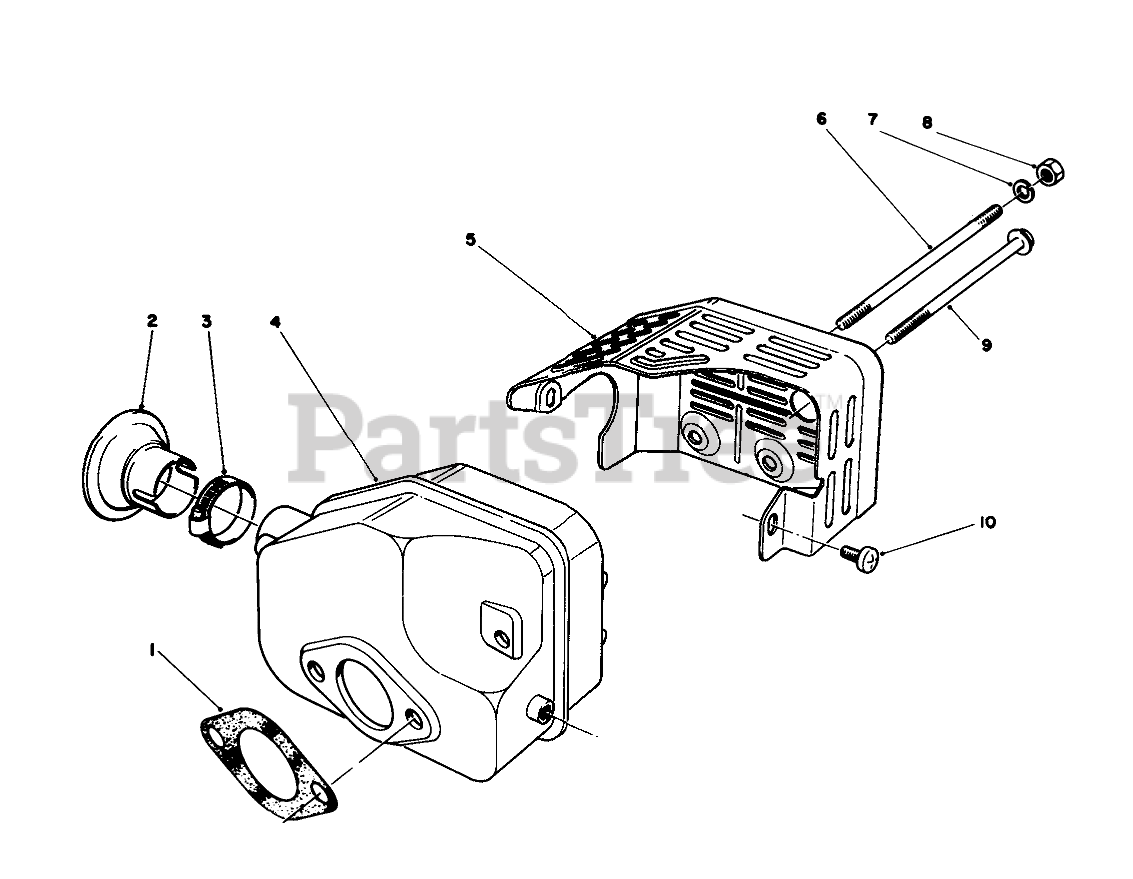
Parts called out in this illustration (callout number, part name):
1	GASKET
2	Arrestor-Spark
3	Clamp
4	Muffler
5	COVER-MUFFLER
7	110 Nut
8	110 Nut
9	110 Nut
10	SCREW
